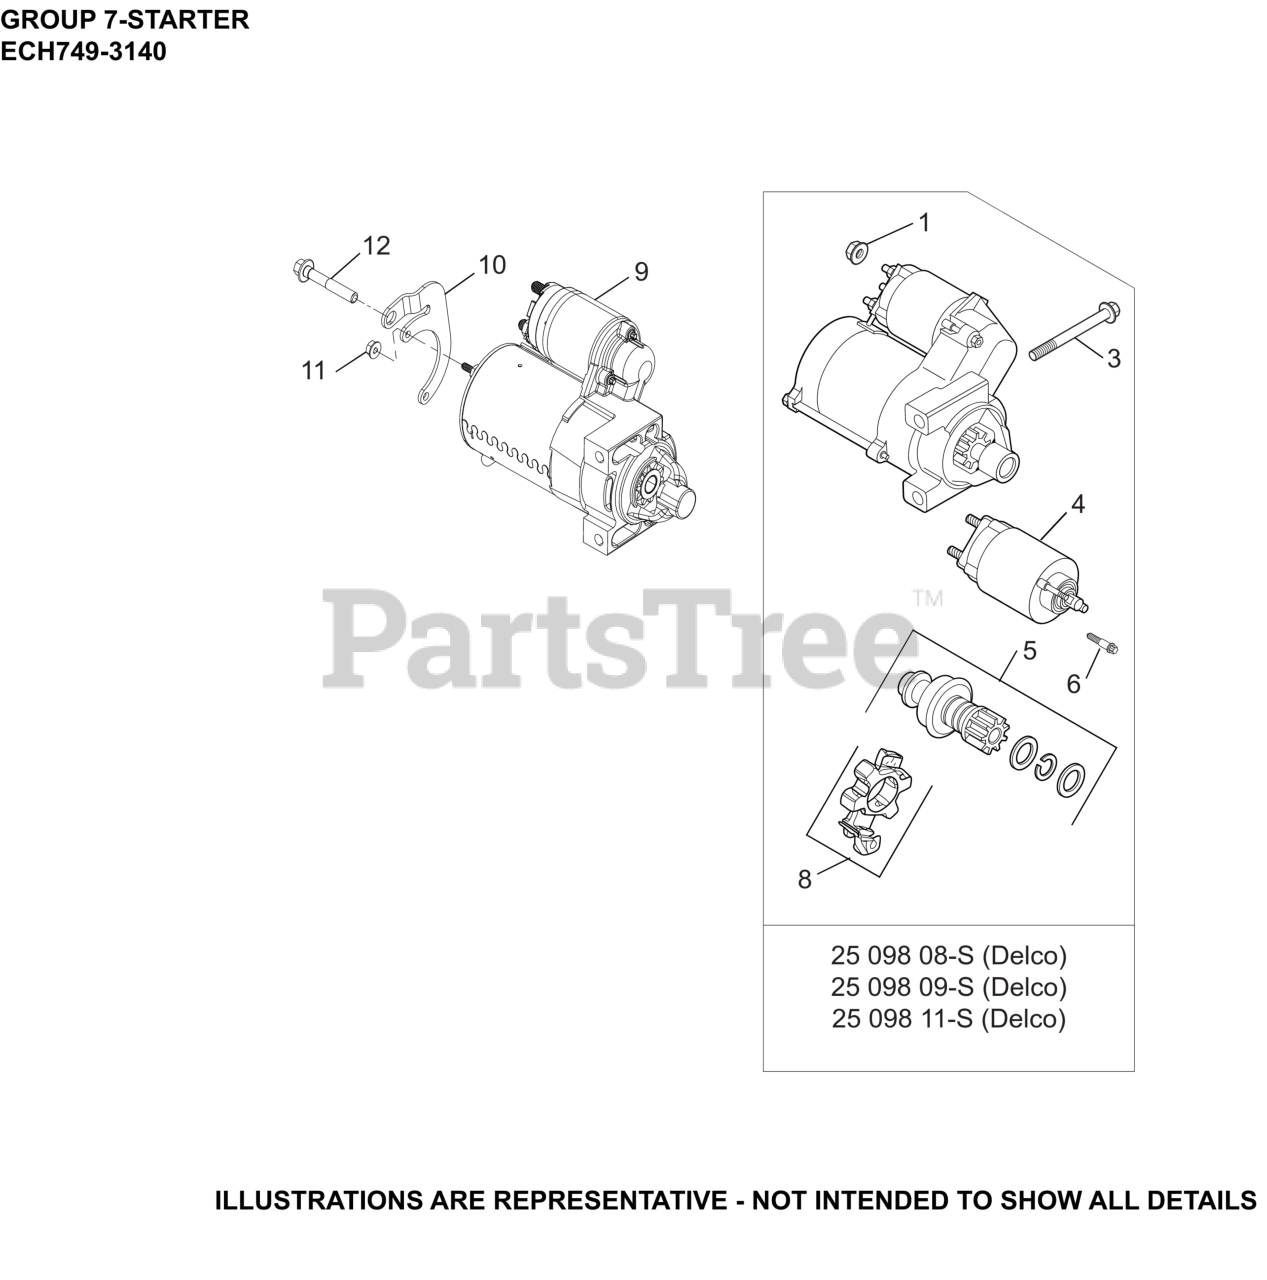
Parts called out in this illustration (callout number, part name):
1	NUT, FLG M8X1.25
3	SCREW, FLG M8X1.25X80
4	KIT, SOLENOID
5	KIT, STARTER PINION-DISCONTINUED
6	SCREW, EXTERNAL TORX HEAD
8	KIT, BRUSH HOLDER
9	ELECTRIC STARTER - SOLENOID SHIFT
10	BRACKET, STARTER MOTOR
11	NUT, HEX FLANGE LOCK (10-24)
12	SCREW, HEX FLANGE
